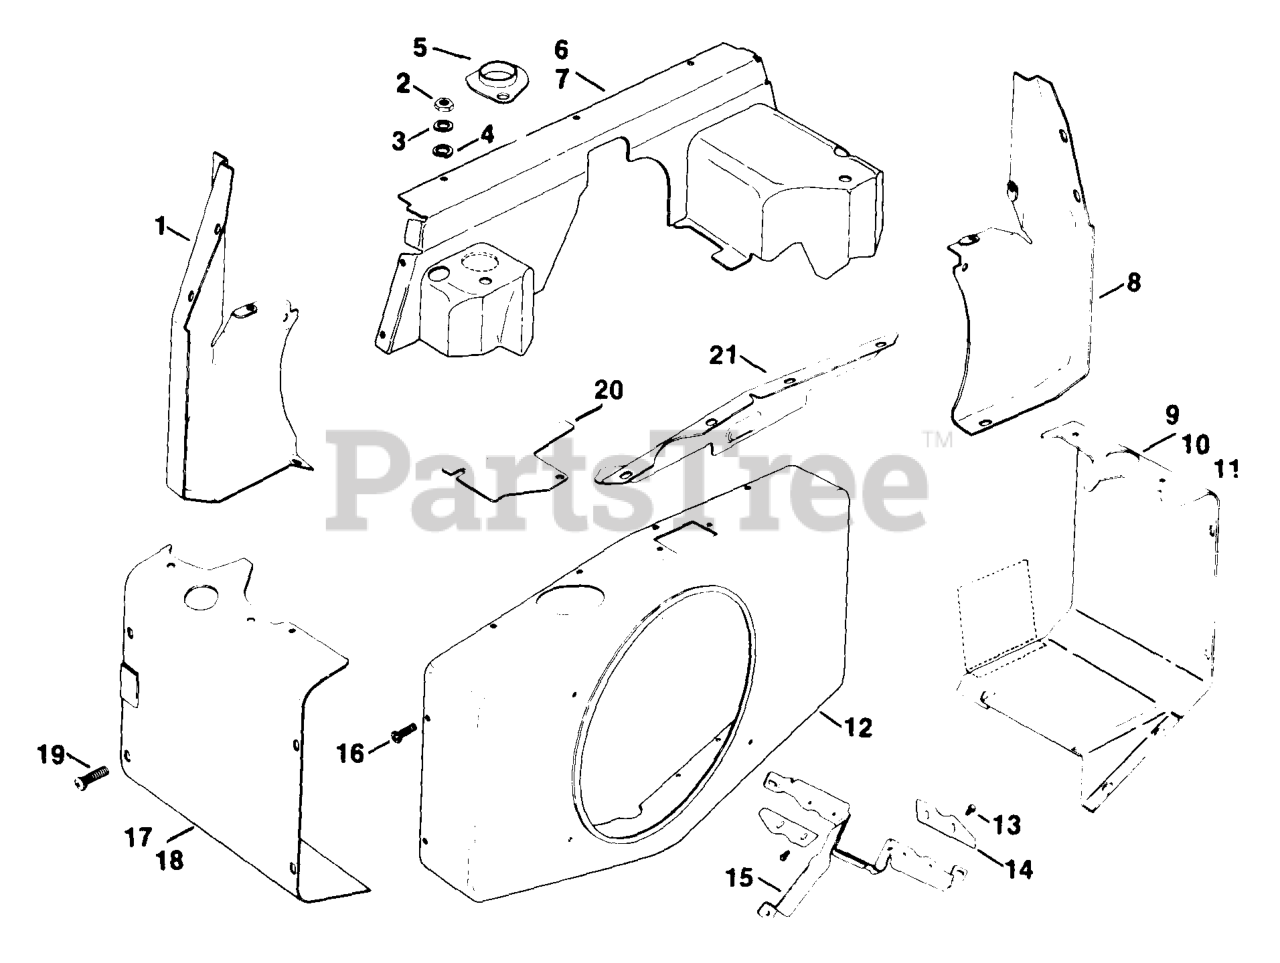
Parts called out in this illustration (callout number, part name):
9	BAFFLE - DISCONTINUED
12	HOUSING - DISCONTINUED
16	Screw, hex. wash. hd. 1/4-20 x 7/16
17	BAFFLE - USE 52 124 30
20	BAFFLE, FUEL PUMP - (#DSC)
21	SUPPORT - (#DSC)
